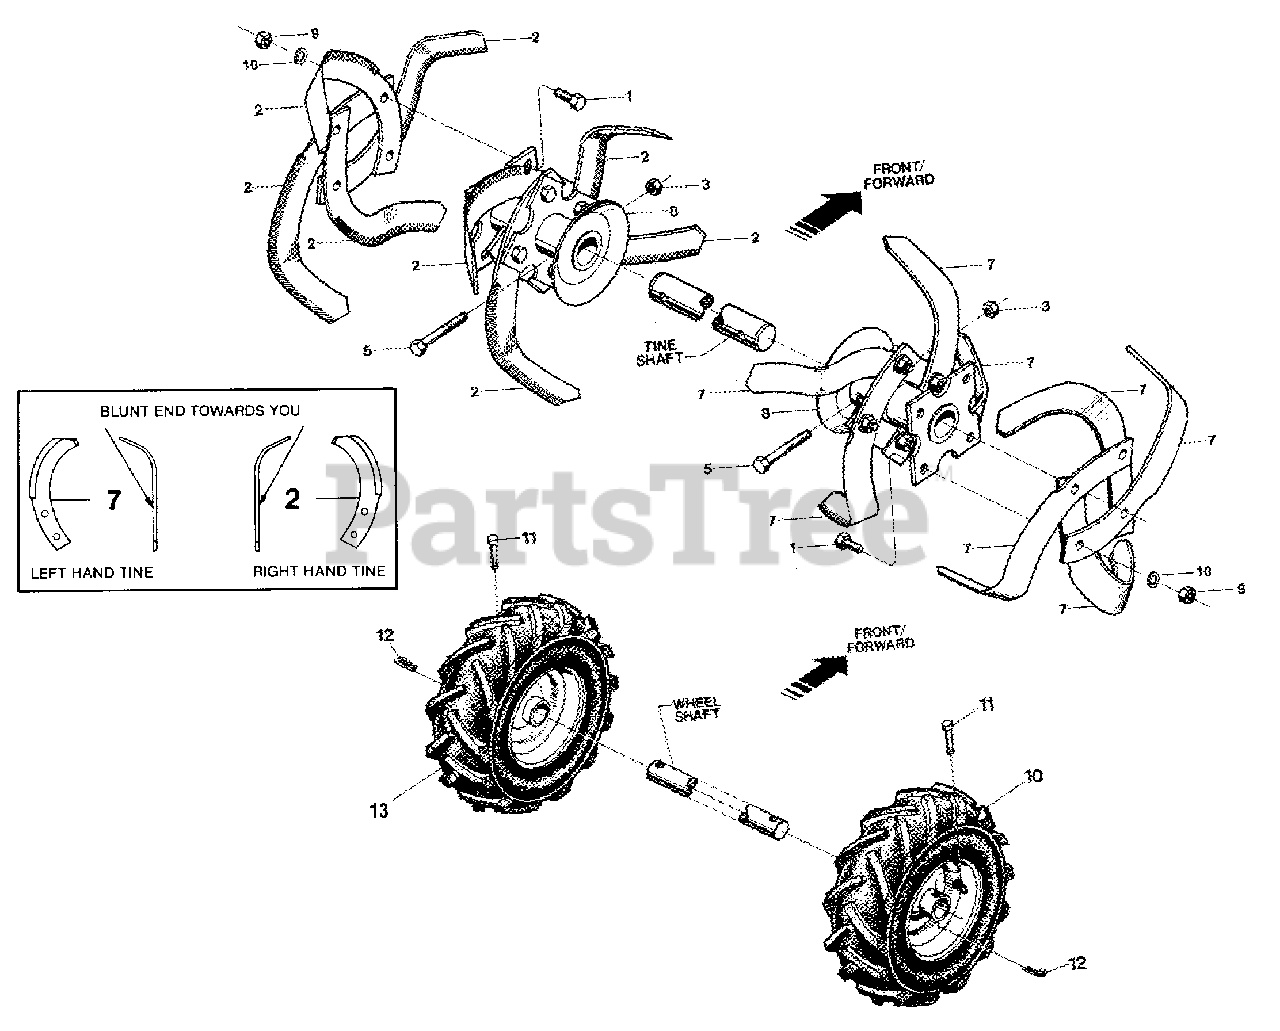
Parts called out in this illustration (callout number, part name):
1	Hex Hd. Screw, 3/8-16 x 1-1/4
2	Bolo Tine - single, right hand tine used on left side of tiller
3	Hex Locknut, 3/8-16
5	Hex Hd. Screw, 3/8-16 x 2, GRADE 8
7	Bolo Tine - Single, left hand tine used on right side of tiller
8	Tine Holder-for bolo tines, left and right sides
9	Hex Nut, 3/8-16
10	Lock Washer, 3/8
11	Clevis Pin-.312 x 1-3/4 long
12	Hitch Pin
13	Wheel & Tire Assembly
